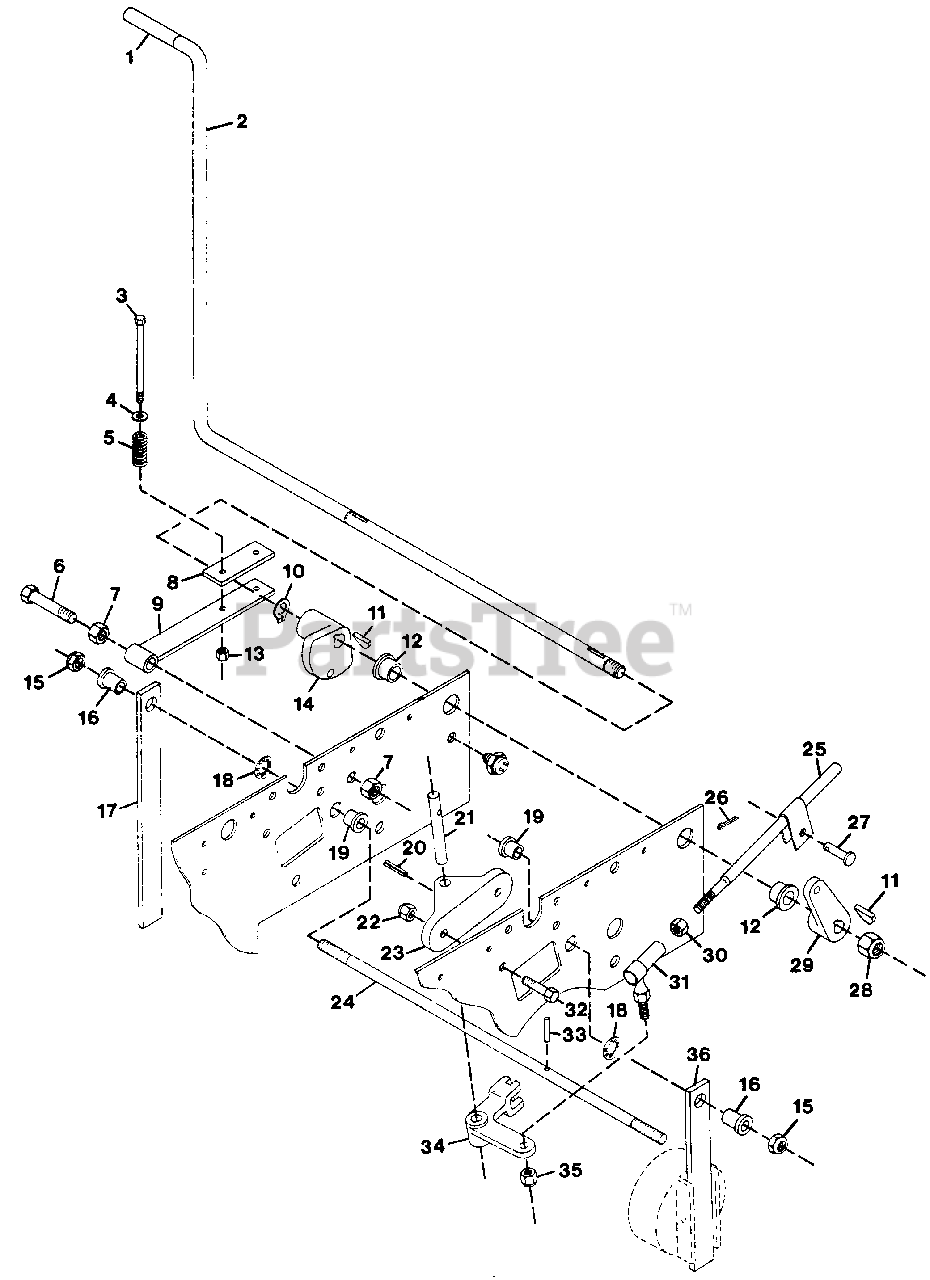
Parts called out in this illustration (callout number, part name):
1	Grip, Handle
2	Lever, Fwd-Rev
3	Bolt, Hex 5/16-18x3.25
4	Washer, Flat .344x.688x.065
5	Spring, Comp. 1.00x.78x338 lb/in
6	Bolt, Hex 1/2-13x2.50
7	Nut, Hex 1/2-13
8	Plate, Clutch Detent
9	Weldment, Clutch Detent Spring
10	Ring, Retaining .750 Shaft
11	Key, Woodruff .187x.625 Hrd #61
12	Bushing, Nylon .76x1.00x.60 Flg.
13	Nut, Lock 5/16-18
14	Hub, Interlock
15	Nut, Lock 1/2-20
16	Bushing, Fwd-Rev Slide Rod
17	Spring, Fwd-Rev Clutch
18	Ring, Retaining
19	Bushing, .513x.750x.625
20	Pin, Spring .187x1.00
21	Pin, Pivot
22	Nut, Lock 3/8-16
23	Bracket, Clutch Arm
24	Rod, Fwd-Rev Clutch
25	Weldment, Fwd-Rev Assembly
26	Pin, Cotter .09x.75
27	Pin, Clevis .375x.948
28	Nut, Lock 5/8-11
29	Lever, Fwd-Rev
30	Nut, Hex 3/8-24
31	Ball Joint, Steering
32	Bolt, Hex 3/8-16x.875
33	Pin, Dowel
34	Lever, Slide Rod
35	Nut, Lock 3/8-24
36	Spring, Reverse Clutch
